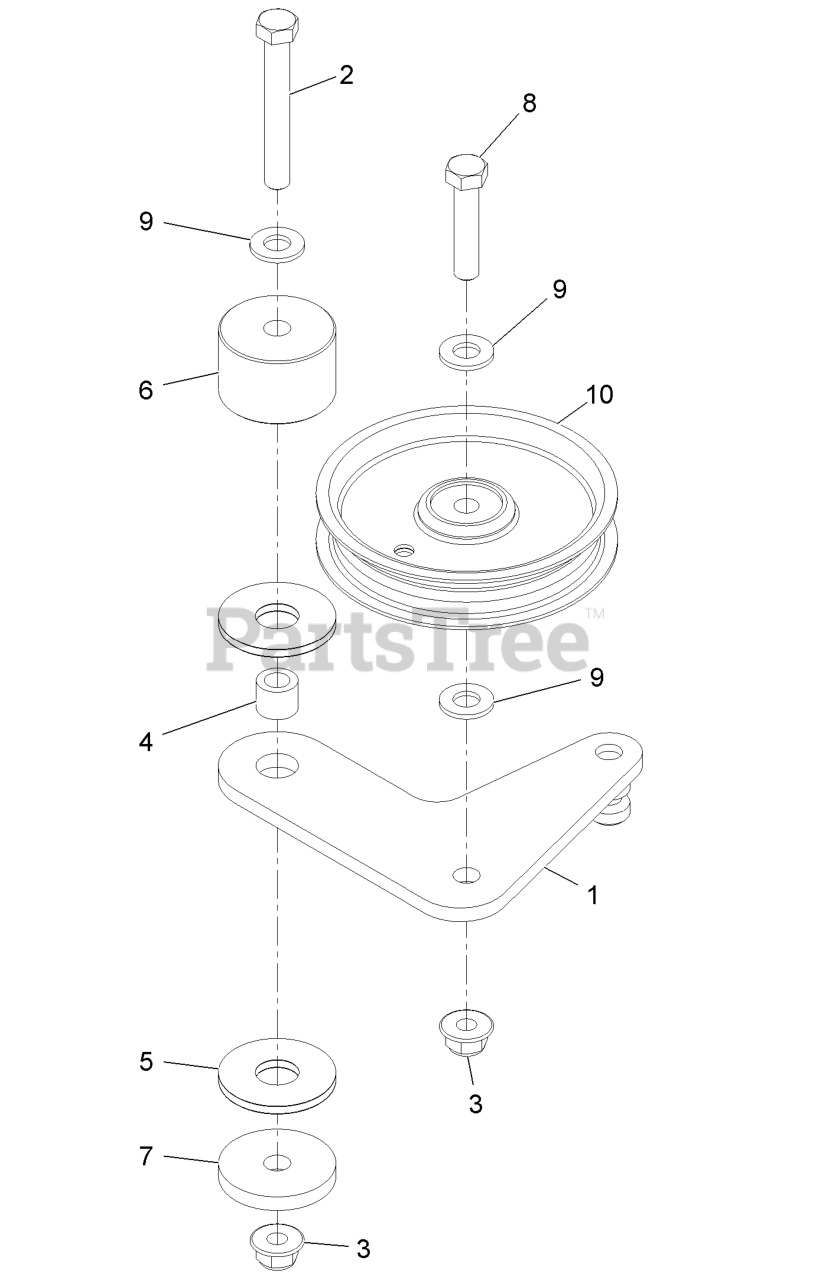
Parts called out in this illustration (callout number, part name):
1	PLATE-IDLER
2	SCREW-HH
3	NUT-HF, NI
4	BUSHING-LEVER, LIFT
5	WASHER-FRICTION, COMPOSIT
6	HUB-IDLER
7	WASHER-PLAIN
8	SCREW-HH
9	WASHER-FLAT
10	PULLEY-IDLER
